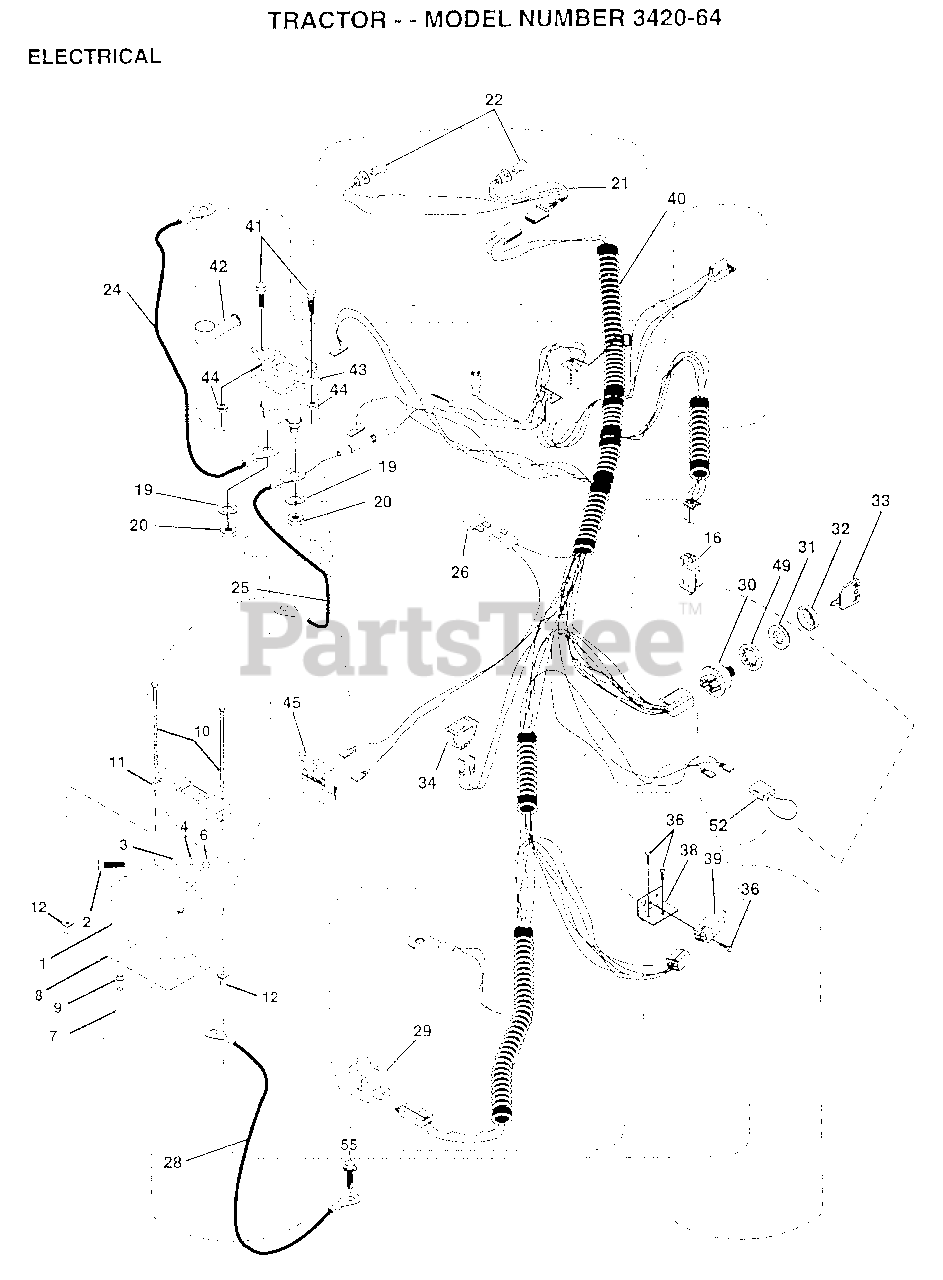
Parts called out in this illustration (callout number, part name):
2	BOLT LT
3	WASHER
4	LOCKWASHER
7	"DRAIN TU T, BATT"
8	"TRAY T, BATTERY"
9	HOSE CLAMP T
16	SWITCH INTERLOCK
20	NUT
21	"HARNESS,LIGHT SOC"
22	HEADLAMP BULB
24	CABLE.6GA.22W/16W
25	"CABLE T, BATTERY"
26	FUSE HYT
28	CABLE.GRND.6GA.21
29	SWITCH SEAT
32	COVER KEY SWITCH
33	KEY MLD GEN DELTA
34	SWITCH LT
36	SCREW
38	BRACKET SWITCH IN
39	SWITCH INTERLOCKT
40	HARNESS.IGN.MECH.
41	BOLT HXHD FIN
44	NUT HXKEP 1/4X20
49	WASHER PINNED
52	PROTECTION LOOP
55	SCREW LT
70	HARNESS ENG DUAL
